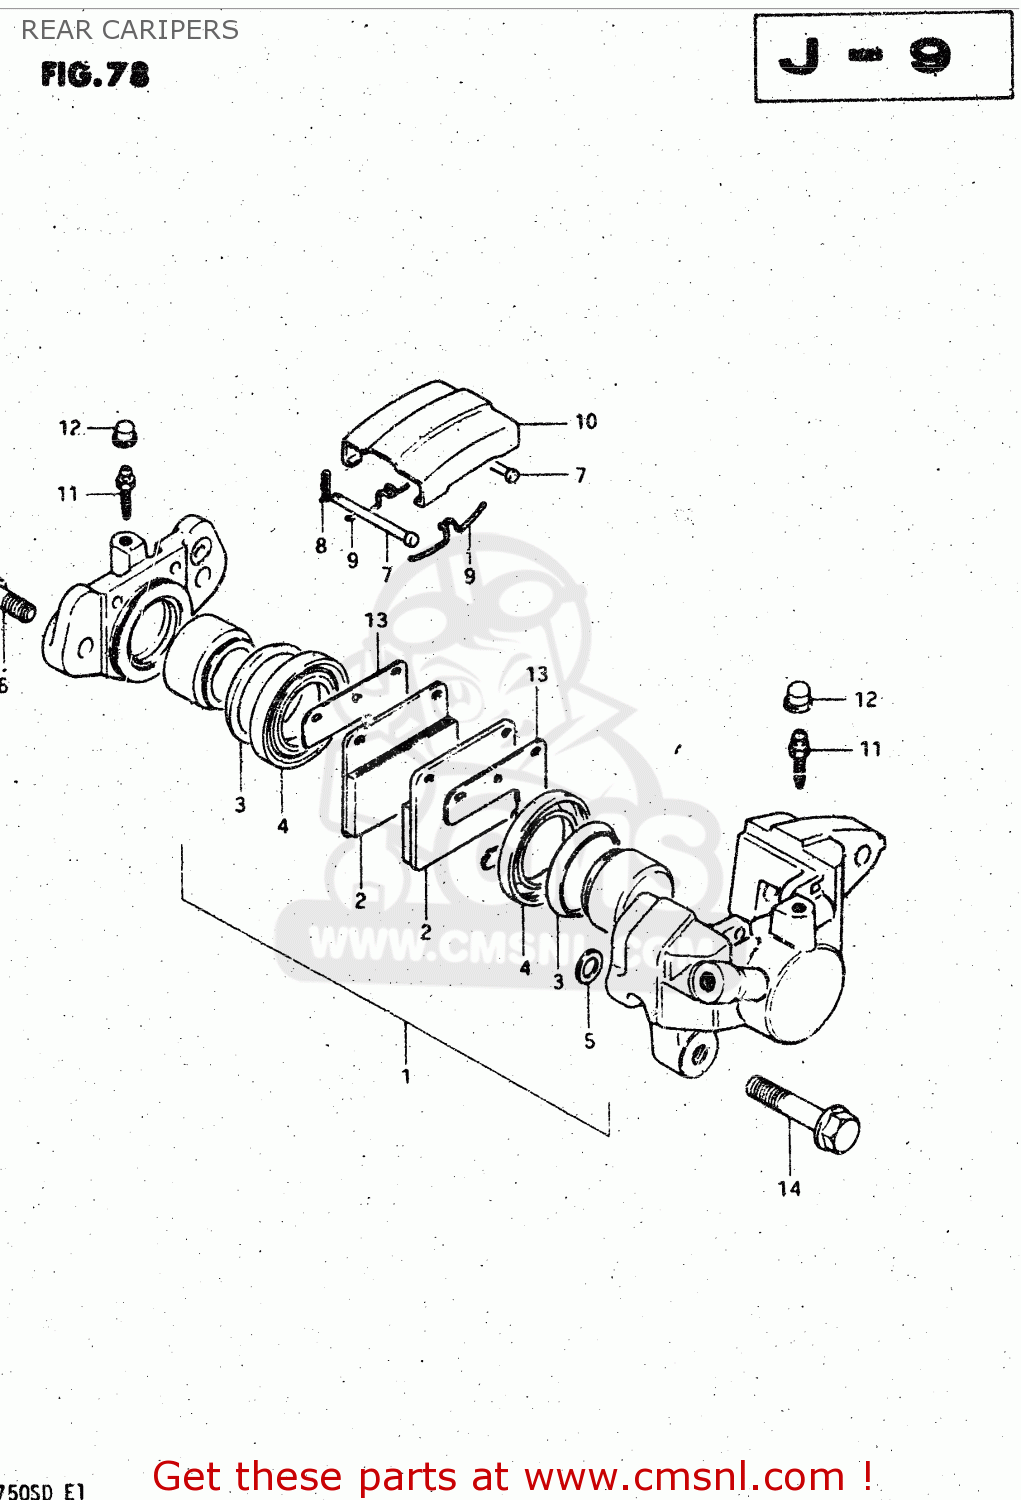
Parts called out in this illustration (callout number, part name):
1	PISTON SET
2	PAD,BRAKE
3	SEAL,PISTON
4	BOOT,PISTON
5	SEAL,PISTON
6	BOLT,HOUSING
7	PIN,PAD
8	CLIP,PAD PIN
9	SPRING
10	COVER,DUST
11	BLEEDER
12	CAP,BREATHER
13	SHIM,RR CALIPER
14	BOLT
